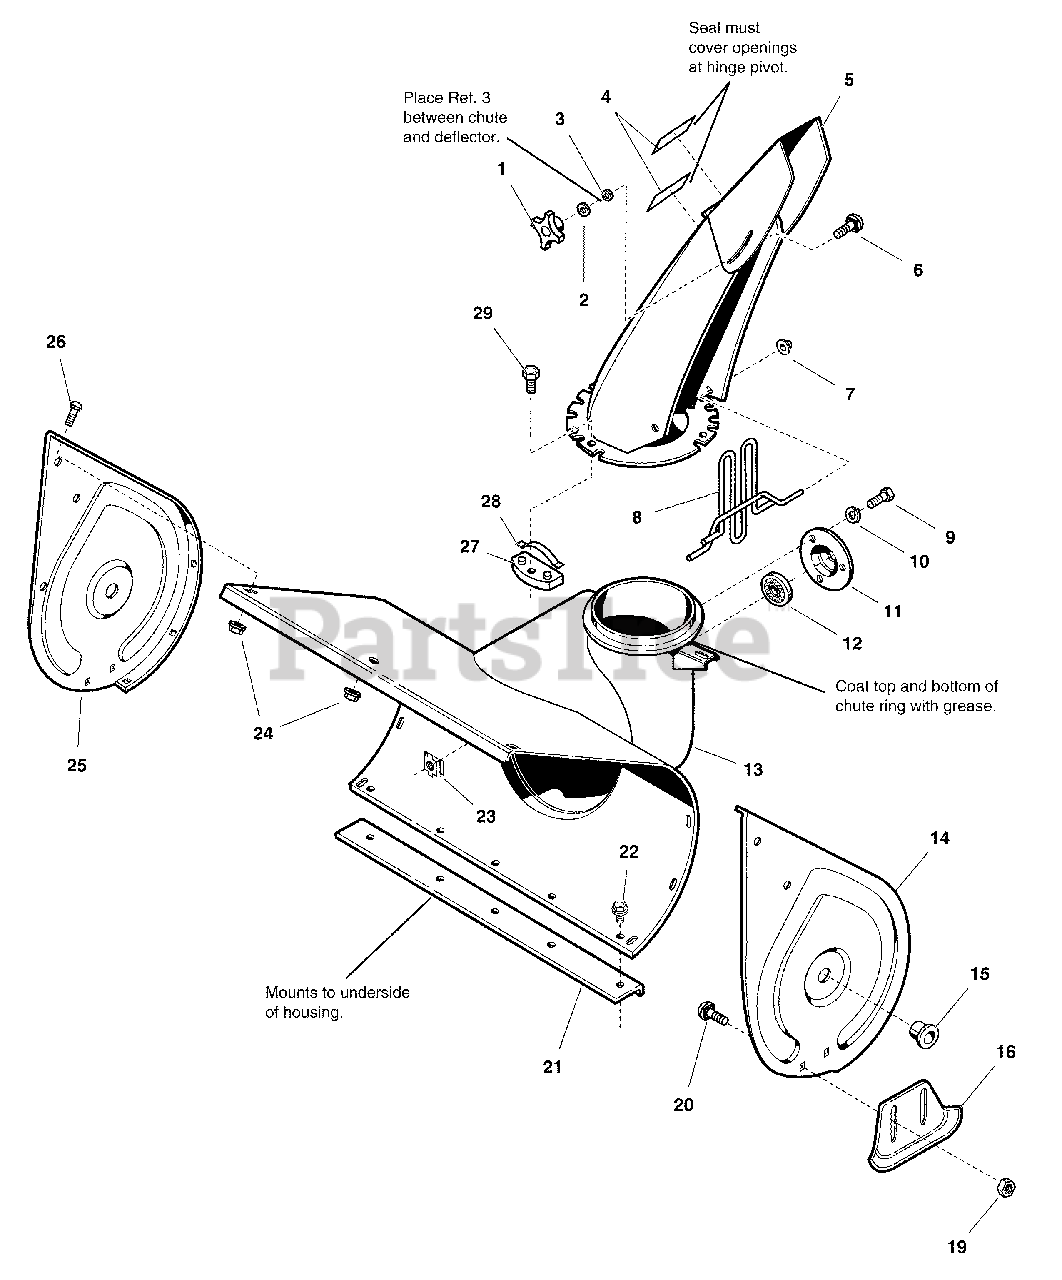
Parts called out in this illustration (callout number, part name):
2	WASHER, Flat, 5/16
3	WASHER, Nylon
4	DECAL, Hinge, Orange
5	CHUTE & DEFLECTOR ASSEMBLY
6	CARRIAGE BOLT, 5/16-18 x 3/4
7	NUT, Push Pas, 1/4
8	CHUTE, Guard
9	CAPSCREW, Hex Hd. 5/16-18 x 5/8
10	LOCKWASHER, 5/16
11	RETAINER, Bearing
12	BEARING, Ball
13	HOUSING ASSEMBLY
14	AUGER PLATE, L.H. End
16	SKID, Snowthrower (Set of 2 available under PN 1685501)
19	NUT, ESNA Flange, 3/8-16
20	CARRIAGE BOLT, Round Head Square Neck, 3/8-16 x 3/4
21	BLADE, Scraper
22	CAPSCREW, Taptite, 1/4-20 x 3/8
23	NUT, Retainer, 5/16-18
24	NUT, Hex Flange, Whiz-Lock, 1/4-20
25	AUGER PLATE, R.H. End
26	CARRIAGE BOLT, 1/4-20 x 1/2
27	HOLD DOWN, Chute
28	SPRING, Flat
29	CAPSCREW, Hex Washer Hd., Plastite #10-14 x 5/8
